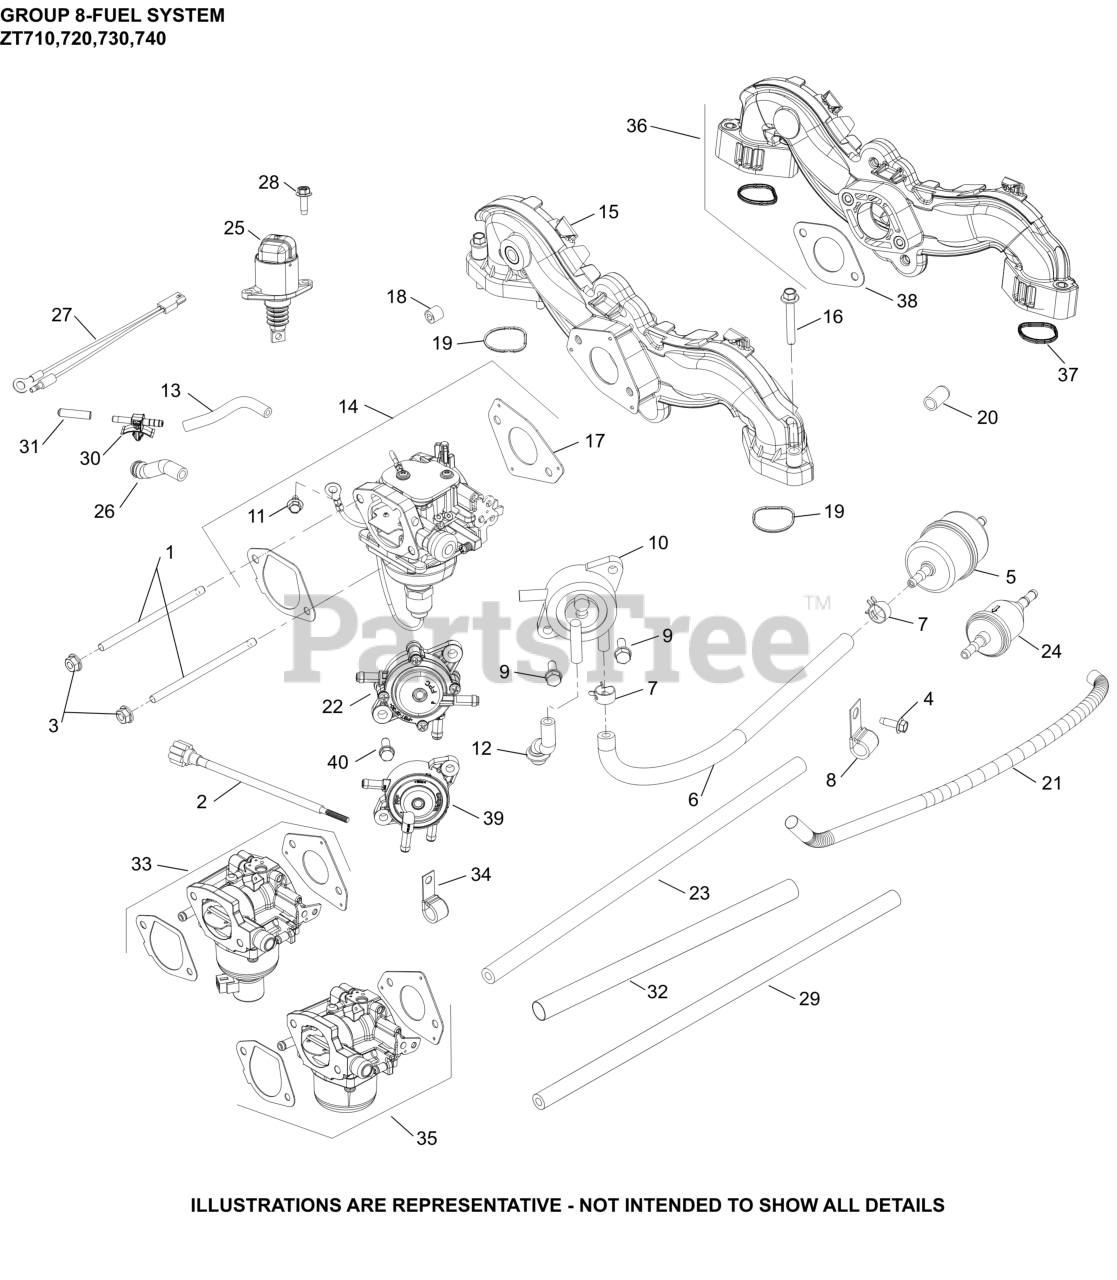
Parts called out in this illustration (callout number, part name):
3	NUT, FLG M6X1.0
5	FILTER, FUEL
7	SPRING CLAMP, HOSE
11	SCREW, THREAD FORMING
16	SCREW, FLG M6X1.0X40
26	HOSE, FP-USE 32 326 07-S(PLASTIC COVERS)
28	SCREW, THREAD FORMING
33	KIT,CARB (NIKKI)
34	CLIP, CABLE (KM)
36	INTAKE MANIFOLD W/GASKETS
37	O-RING, INTAKE PORT
38	GASKET, CARBURETOR (PIM, CV)
39	PUMP, FUEL (PULSE)
40	SCREW, HEX HEAD
NI	KIT, OVERHAUL NIKKI G-TYPE TWIN
NI	KIT, BOWL WITH O-RINGS NIKKI G-TYPE TWIN
NI	KIT, FLOAT AND NEEDLE NIKKI G-TYPE TWIN
NI	KIT,THROTTLE SHAFT(22MM)NIKKI-DISC.
NI	KIT,CHOKEREPAIR NIKKI G-TYPE T-DISC.
NI	KIT,HIGH ALT(22MM) NIKKI-USE 16 755 19-S
NI	KIT, O-RING (NIKKI)
NI	KIT, SOLENOID (NIKKI)
